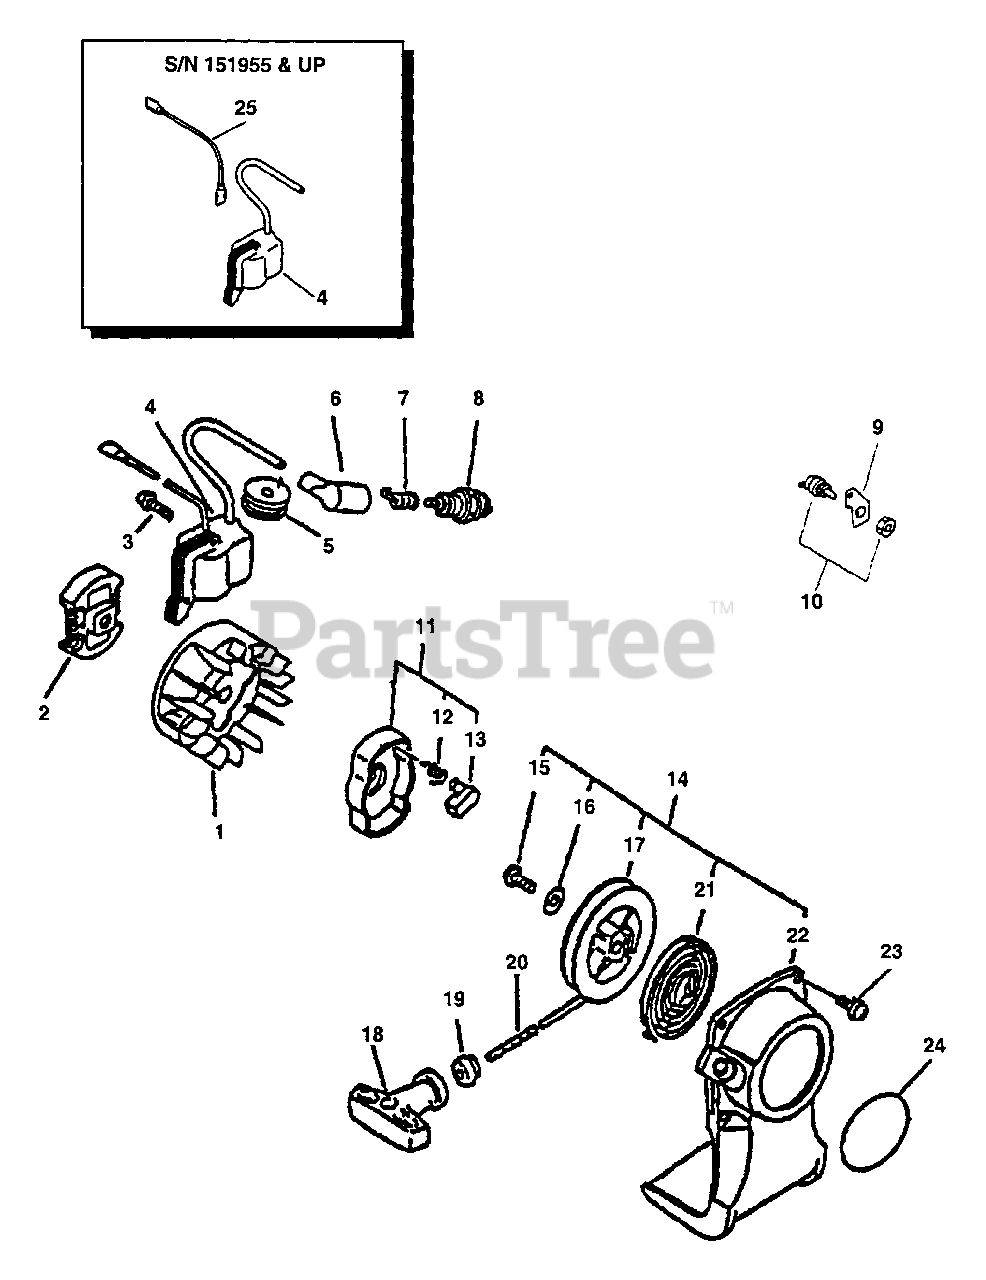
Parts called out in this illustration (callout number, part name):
1	FLYWHEEL
2	CLUTCH ASSY
3	SCREW - 4X22
4	COIL, IGNITION
5	GROMMET
6	CAP, SPARK PLUG
7	TERMINAL, SPARK PLUG CAP
8	SPARK PLUG -- BPM-7A
8	SPARK PLUG -- BPMR-7A
9	BRACKET, SWITCH
10	IGNITION SWITCH ASSY
11	STARTER PAWL ASSY
12	SPRING, RETURN
13	PAWL, STARTER - BLACK
14	STARTER ASSY
16	WASHER
17	REEL, ROPE
18	GRIP, STARTER
19	GUIDE, ROPE
20	ROPE, STARTER - 3X890
21	SPRING, REWIND
22	CASE, STARTER - BLUE
23	SCREW - 4X16
24	LABEL - ECHO
25	LEAD - GROUND
